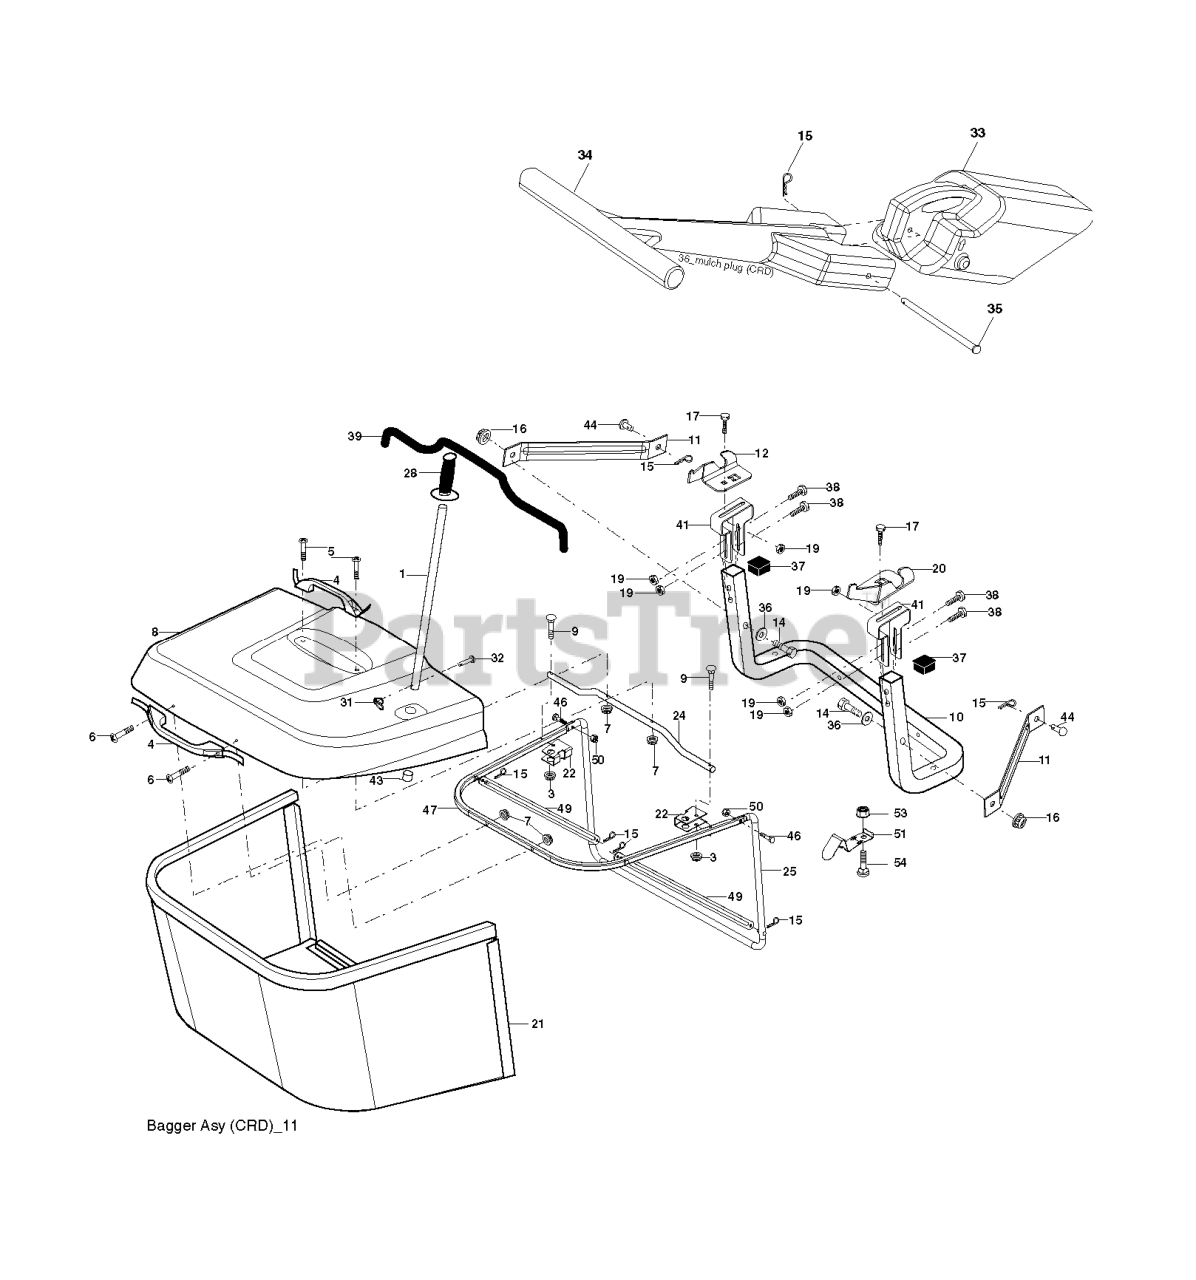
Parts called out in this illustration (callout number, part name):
1	TUBE HANDLE
3	NUT T
4	HANDLE.BAGGER.W/LVRS.BLK.CRD
5	SCREW.PAN.HEAD
6	REPL BY 532 75 00-29
8	COVER.PNT.BGR.CRD.WSLOTS.MS668
9	Bolt Carriage 1/4-20 x 2.25d x Gr.5
10	TUBE
11	BRACKET.SUPPORT.UPPER.BAG.CRD
12	BRKT PIVOT
14	BOLT-HEX EAK
15	RETAINER-SPRNG RB
16	NUT LOCK FLG 3/8-16 UNC
17	RP BOLT 5/16-18 X3/4 ZN/YEL GR
19	NUT LOCK HEX FLANGE 5/16-18
20	BRKT.PIVOT.RH.CRD
21	BAGGER.ASM.CRD.2007
22	BRKT.SIDE.BAG.CRD
24	TUBE.PIVOT.BAG.CRD.BLACK
25	PIPE
28	GRIP.HANDLE.BLACK
31	RETAINER CLIP
32	RIVET,DRILLED
33	MULCH PLUG, CTH150
34	HANDLE.MULCHER.92.CRD (2 2)
36	WASHER
37	Plug Support Bagger CRD
38	BOLT.5/16-18X2.5
39	SEAL.TRIM.37'
41	BRKT.VERT.ADJ.BAGGER.CRD
43	PLUG, TUBING END
46	BOLT.CARRIAGE.5/16-18
47	PIPE
49	ROD
50	NUT.71038.31-18.HEX.NYLOCK
51	LATCH
53	NUT
54	BOLT
